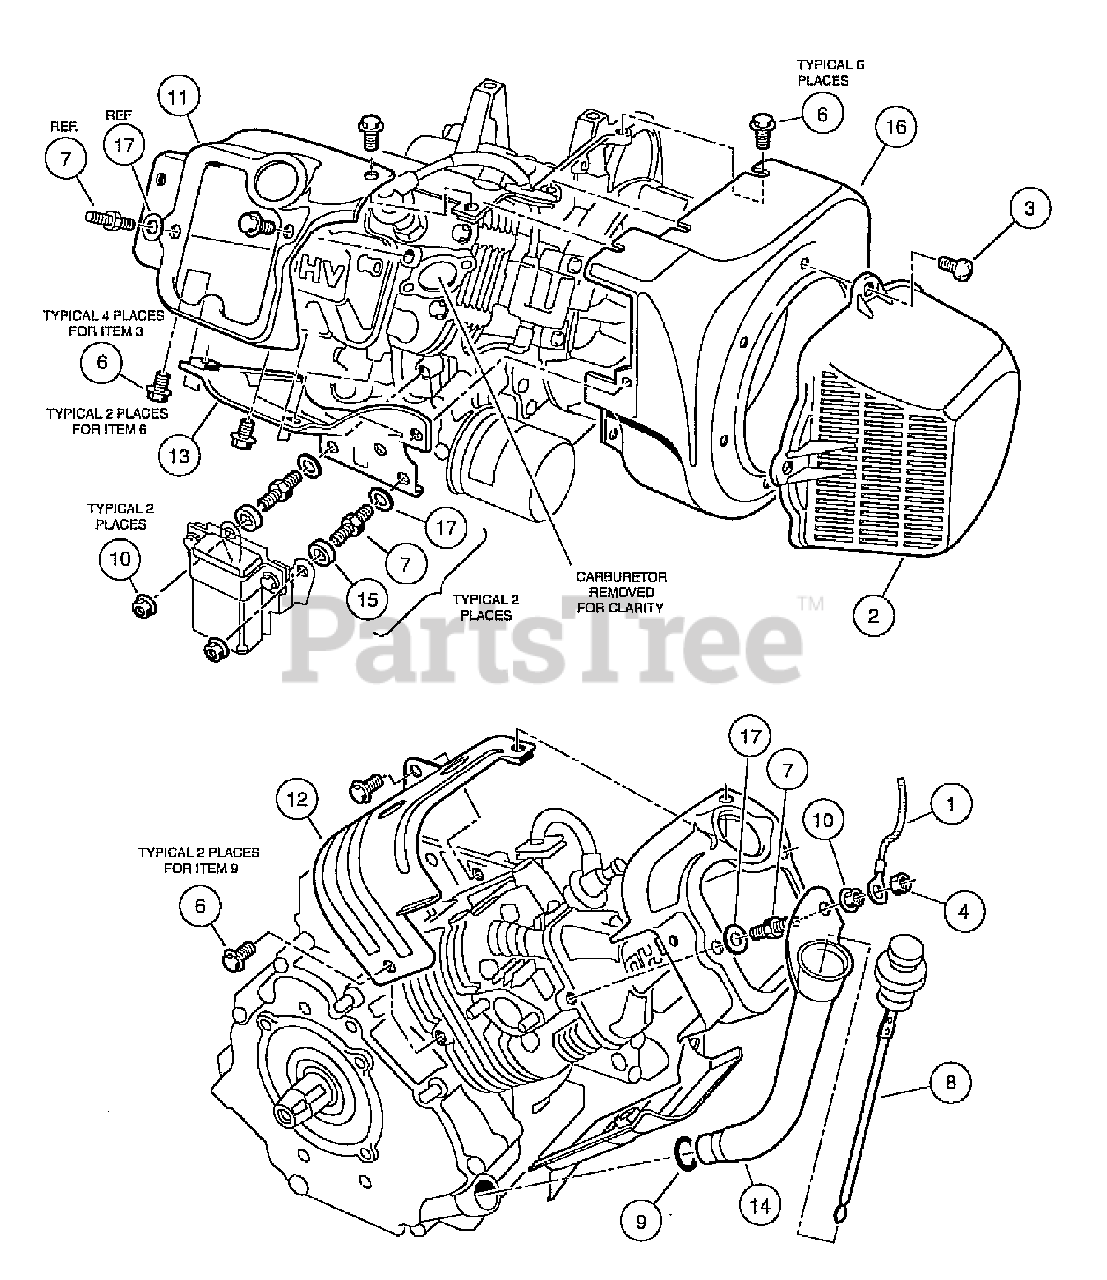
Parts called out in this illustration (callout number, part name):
1	Wire Assembly, #10, Uninsulated
2	Shroud, Fan
3	Screw, M6-1.00 X 10mm Pan Hd
4	Locknut, M6-1.00 Nylon Insert
5	Engine, Fe350 Cw W/o Comp.rel
6	Bolt, Flange Head, M6 x 1 x 12 mm
7	Bolt, Two-Ended
11	Shroud, Engine
12	Shroud, Engine
13	Shroud, Engine
14	Tube, Oil Filler
15	Spacer 6.50 X 12 X 5.5
16	Housing, FE350 Fan
17	Washer, 6mm Flat
